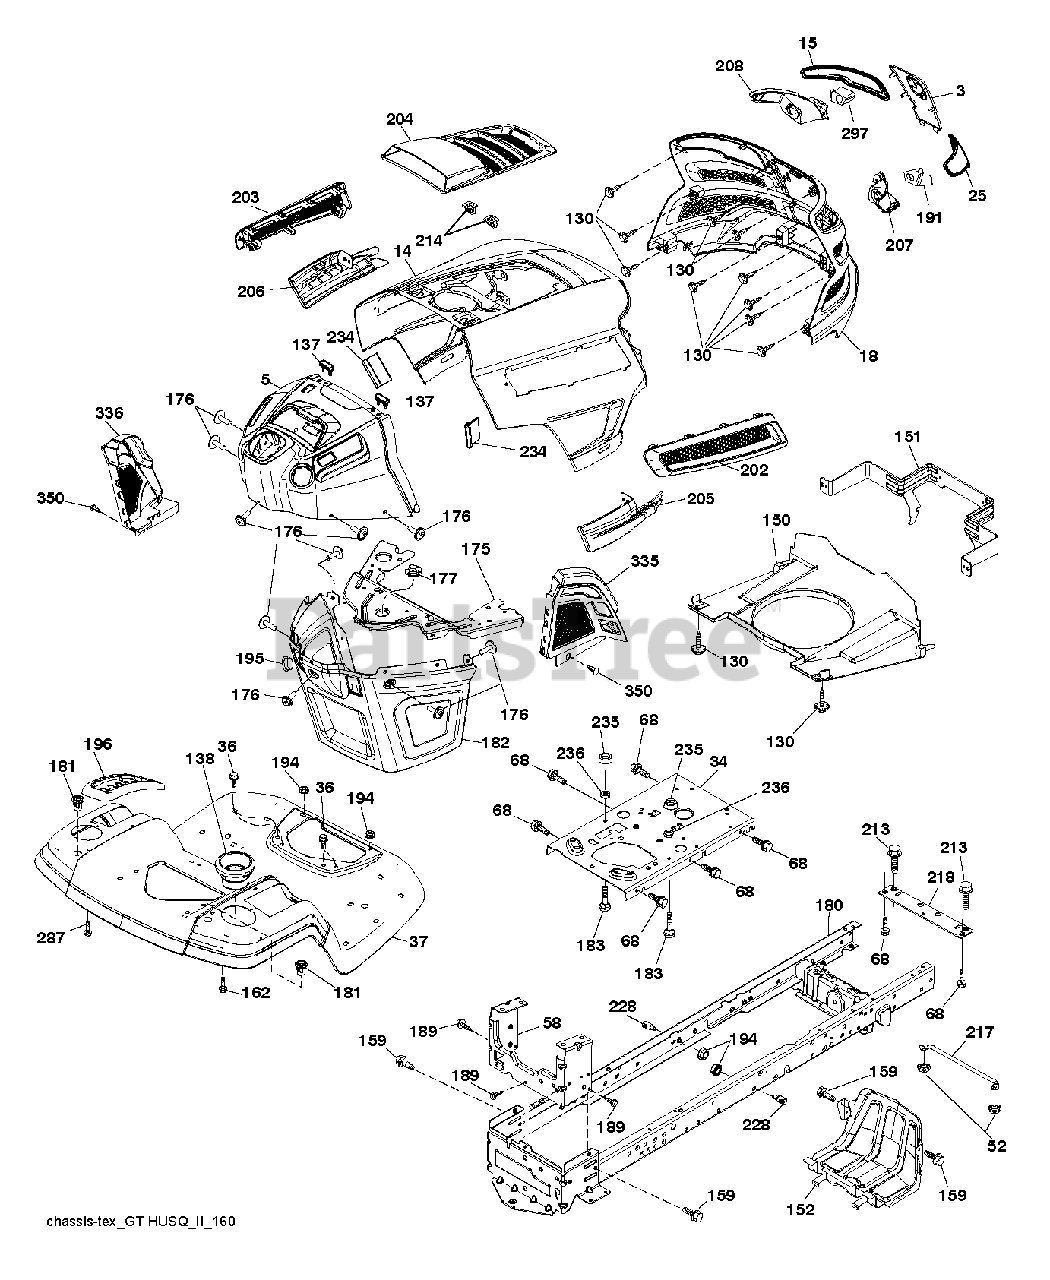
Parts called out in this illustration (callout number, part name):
3	APPLIQUE.SUBASM.GT.HUSQ.II
5	UPPER.ASSY.GT2.498.GRY
14	HOOD.ASM.HUSQVARNA.GT.TEX.ORAN
15	LENS.HEADLIGHT.LH.GTII.2011
18	GRILLE.SUBSTRATE.2011.
25	LENS.HEADLIGHT.RH.GTII.2011
34	PLATE.ENGINE.WELDED.CHASSIS
36	SCREW 5/16"
37	FENDER.TLT.PDL.CNTRL.W/CPH.ORG
52	LOCKNUT
58	DRAWBAR UPPER 2PC SMALL FENDER
68	SCREW LT
130	SCREW.#10 X 0.750.BOS
137	BUMPER DASH
138	HOLDER.CUP.LT.GREY
150	AIR.DUCT.GTV2(2.54"RING HEIGHT
151	BRACKET.PIVOT.HOOD.GT.HUSQ.II
152	SHIELD.BROWNING.PNT.GT.V2
159	SCREW, 3/8-16X3/4
162	SCREW.HI-LO.CONSOLE
175	PLATE.CROSSMEMBER.HUSQ
176	SCREW.#10-24X5/8.RN.QU
177	BUSHING, STEERING
180	CHASS.WLDMNT.TL.12GA/2P.48/54
181	BUSHING.MNT.FEND.CRGO.TEX.49
182	DASH.LOWER.COMMON.12V.ADAPTOR
183	BOLT.5/16-18X1-1/4 FULL THD
189	SCREW
191	INSERT.REFLECTIVE.RH.HUSQ.GTII
194	NUT LOCK HEX FLANGE 5/16-18
195	PLUG.HOLE.DASH.LOWER.12V.BLK
196	DECKLFT.CONSOL FULL ASSM GREY
202	VENT.SIDE.RH.GT.HUSQ.II.
203	VENT.SIDE.LH.GT.HUSQ.II.498
204	VENT.TOP.HUSQ.GT2
205	SIDE.TRIM.RH.GT.HUSQ.II
206	SIDE.TRIM.LH.GT.HUSQ.II.GRAY
207	BEZEL LIGHT.RH.GT.II.MYLAR
208	BEZEL LIGHT.LH.GT.II.MYLAR
213	BOLT
214	CLIP.RETAINER.TINNER.
217	ROD.PIVOT.HOOD
218	X-PIECE.HOOD.STOP.NON/
228	STUD.FASTNER.W/ANTI-ROTATE
234	BUMPER.HOOD.TEX.HUSQVARNA
235	SPACER FENDER
236	NUT.CENTERLOCK.5/16-
287	SCREW 1/4X20
297	INSERT.REFLECTIVE.LH.HUSQ.GTII
335	COVER.LOWER.DASH.RH.BLACK
336	COVER-LH.LOWER.DASH.GT2.BLACK
350	CLIP.X-MAS.TREE
